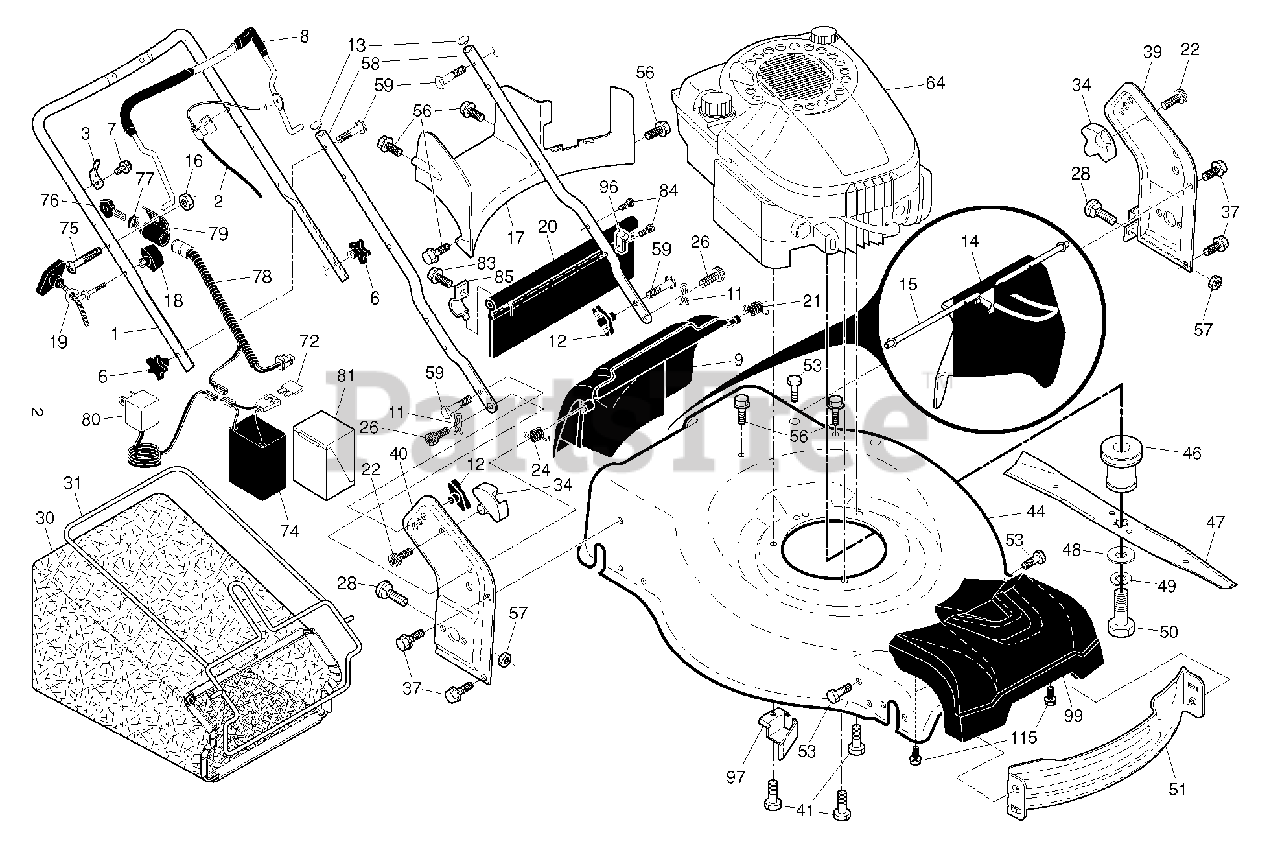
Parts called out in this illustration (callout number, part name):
1	HANDLE.UPPER.3.POS.BS.AW2.GREY
2	CABLE.MZR.50.SNAP-IN
3	BRACKET.UPSTOP.RT
6	KNOB.HANDLE.PLASTIC.STAR.BLACK
8	BAIL.OVER.MOLD.ERGO.MZR.ORANGE
9	DOOR.REAR.ASM.22+.HUSQ.FG/RGD
11	COTTER.HAIRPIN.DOOR/HANDLE.PIV
12	KNOB, DEFLECTOR
13	PLUG.PLASTIC.7/8".14-20.GAUGE
14	DEFLECTOR.CHUTE.22+REAR
15	HANDLE DEFLECTOR.22+REAR
16	NUT
17	BAFFLE.REAR.22+RGD.AWD.PLASTIC
18	T-KNOB.NEW ROPE GUIDE
19	GUIDE.ROPE.BLK.ZINC.CHROM
20	SKIRT.REAR.22PLUS.RGD.LW(2 2MC
21	SPRING.LH.BLACK
22	SCREW.PAN.HEAD.#10
24	SPRING.RH.GRAY
26	SCREW,DOOR/HANDLE.PIVOT
28	BOLT.CARRIAGE.LN.5/16-18X.5/8
30	GBAG.A361029ER.HUSQ.GRY/SIL
31	FRAME.GBAG.22+.BLK
34	BRACKET.GRASSBAG.ATTACHING.BLK
37	BOLT.5/16HEX.WHS.HD
39	BRACKET.ASM.HANDLE.LT.22+.GREY
40	BRACKET.ASM.HANDLE.RT.22+.GREY
41	BOLT 3/8-16X1-1/8
44	HOUSING.22+RG.HD.WO.ORG.TRI.SB
46	ADAPTER.BLADE.25MM.3MPH
47	BLADE.22+.PREMIUM/PREC.FGD/RGD
48	WASHER,HARDEN
49	LOCKWASHER
50	SCREW, HEX HD 3/8-24 X 1-3/8
51	BAFFLE.FRONT.22.PLUS
53	SCREW.HI-LO.5/16 X.75
56	SCREW.HX.13X.750
57	NUT.FLANGE.5/16
58	HANDLE.LOWER.22+BT.2PC.GRY
59	BOLT, HANDLE 5/16-18X1.75
74	BATTERY.12V.22+RWGD
75	SCREW.(COMBINATION CONTROL)
76	KEY.MOLDED
77	NUT.CAP.SNAP-ON.KEY START
78	HARNESS.22+.BATTERY.RWGD
79	HOUSING.WIRING.HARNESS
80	RP CHARGER.12V.0.1A
81	COVER.BATTERY.BOX 22+RDG.GRY
83	TAPPING SCREW
84	FASTENER.PUSH.O.250X0.783
85	BRACKET.SKIRT.22+.BZP
96	CLIP.CABLE.BLK
97	BRACKET.BELT.GUIDE.22+.BZP
99	COVER.ASM.FRONT.HUSQ.22+RGD
115	SCREW.HI-LO. 5/16 X 1.00
